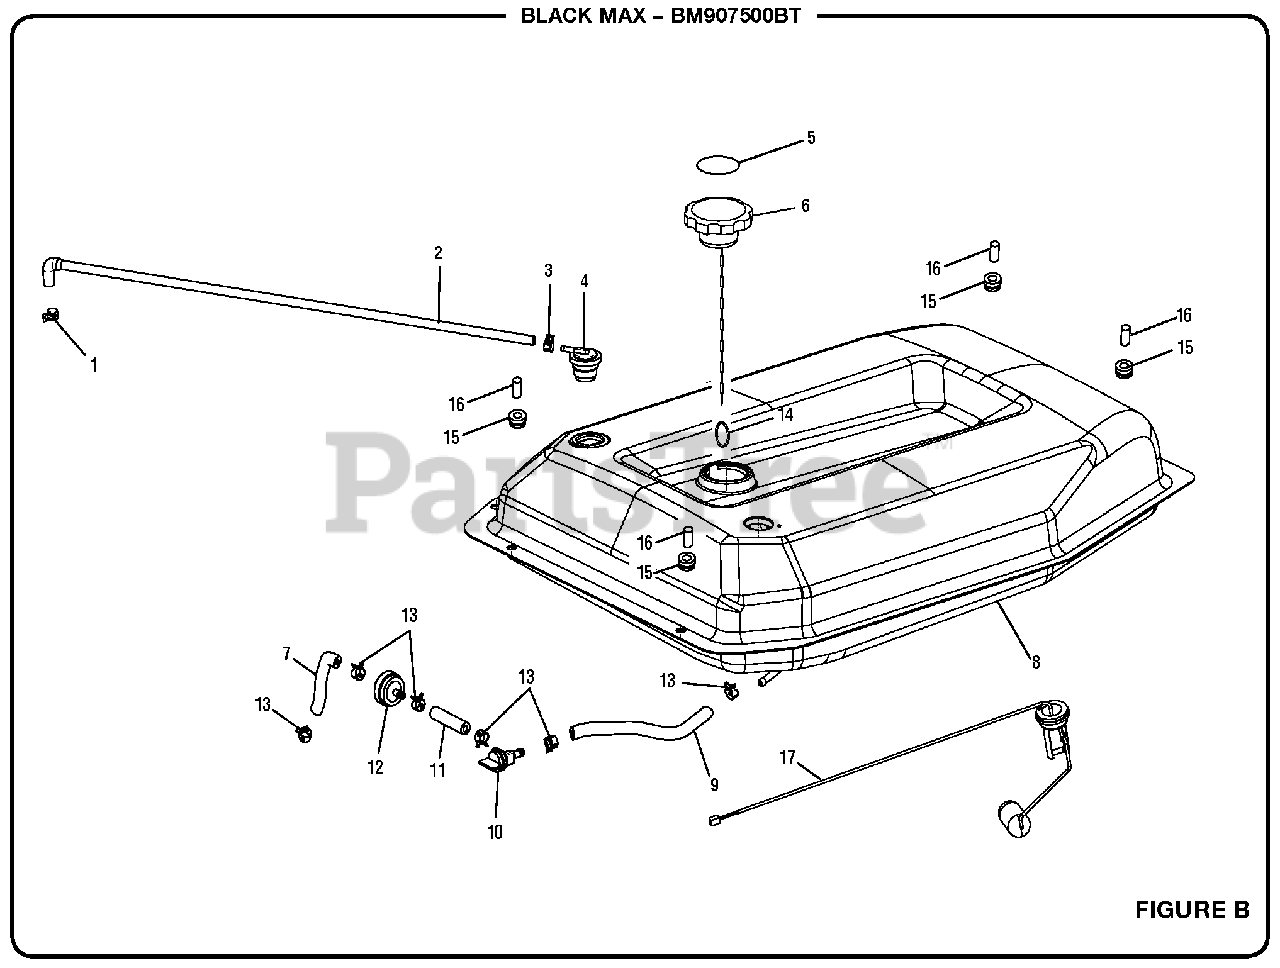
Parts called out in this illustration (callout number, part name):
1	Fuel Line Clamp (10.3 mm)
2	Vapor Hose (590 mm and 30 mm)
3	Fuel Line Clamp (5/16 in.)
4	Vapor Vent
5	Fuel Stabilizer Label
7	Fuel Hose (185 mm)
8	Fuel Tank
9	Fuel Hose (175 mm)
10	Fuel Valve
11	Fuel Hose (55 mm)
12	Fuel Filter
13	Fuel Line Clamp (1/2 in.)
14	Ring Clip
17	Fuel Level Sensor
